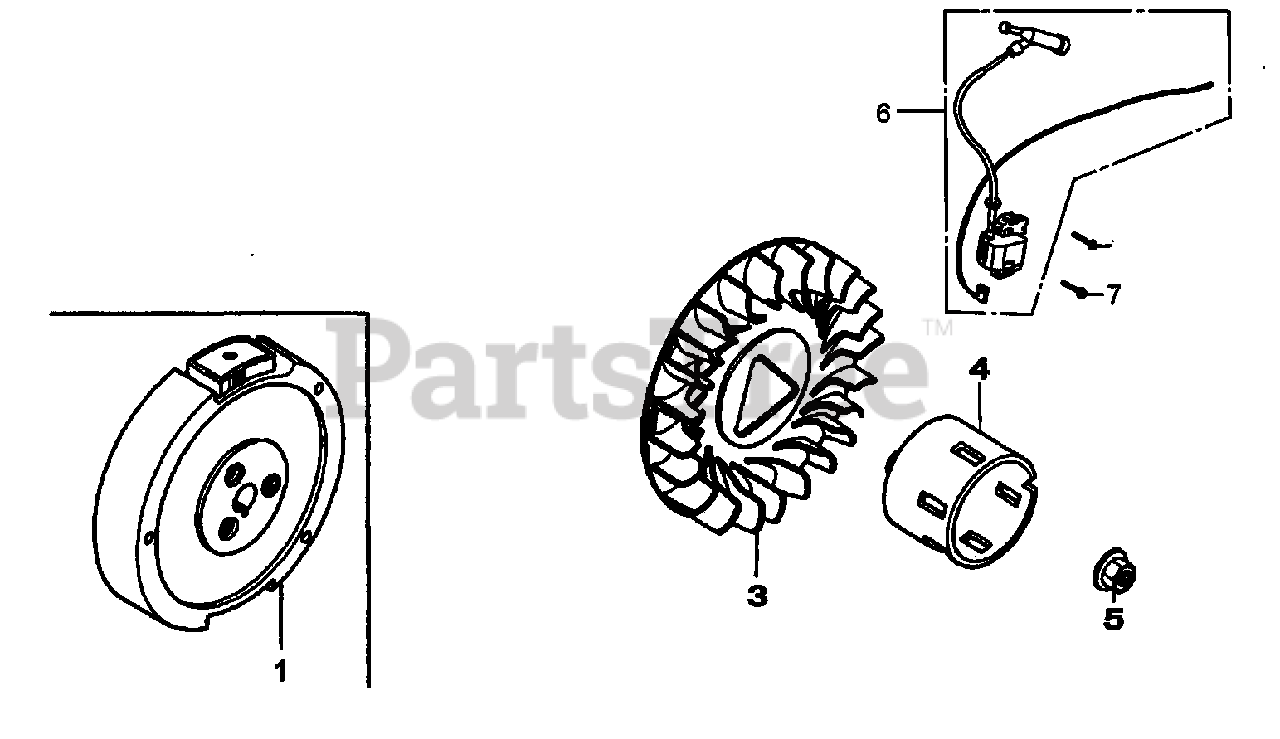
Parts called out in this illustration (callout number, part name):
3	FAN COOLING
4	PULLEY, STARTER
5	NUT SPECIAL, M16
6	COIL ASSY., IGNITION
7	BOLT, FLANGE
